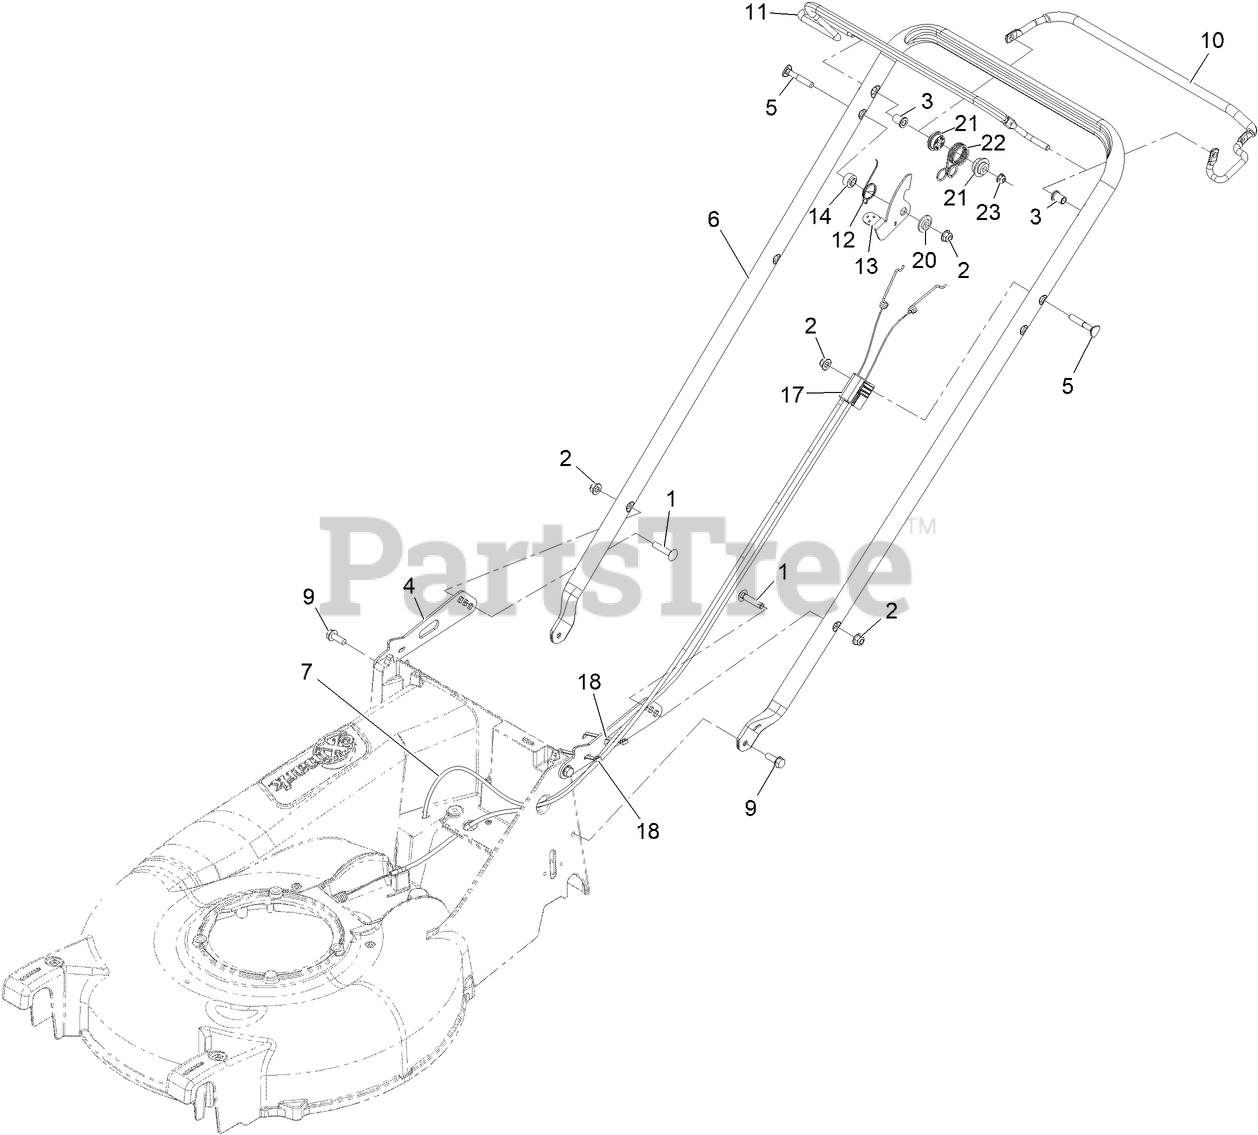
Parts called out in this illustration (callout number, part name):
1	BOLT-CARR
2	NUT-HF, NI
3	BUSHING-HANDLEBAR
4	BRACKET,HANDLEBAR
6	HANDLEBAR-EC21
7	CABLE, DRIVE EC21
9	SCREW-TAPTITE
10	BAIL-DRIVE COATED
12	SPRING-LEVER, BBC
13	LEVER-BBC
14	BUSHING-STEPPED
17	CABLE-BBC
18	TIE-CABLE
20	WASHER-STEPPED
21	BUSHING-SPRING, PIVOT
22	SPRING,BBC RETURN
